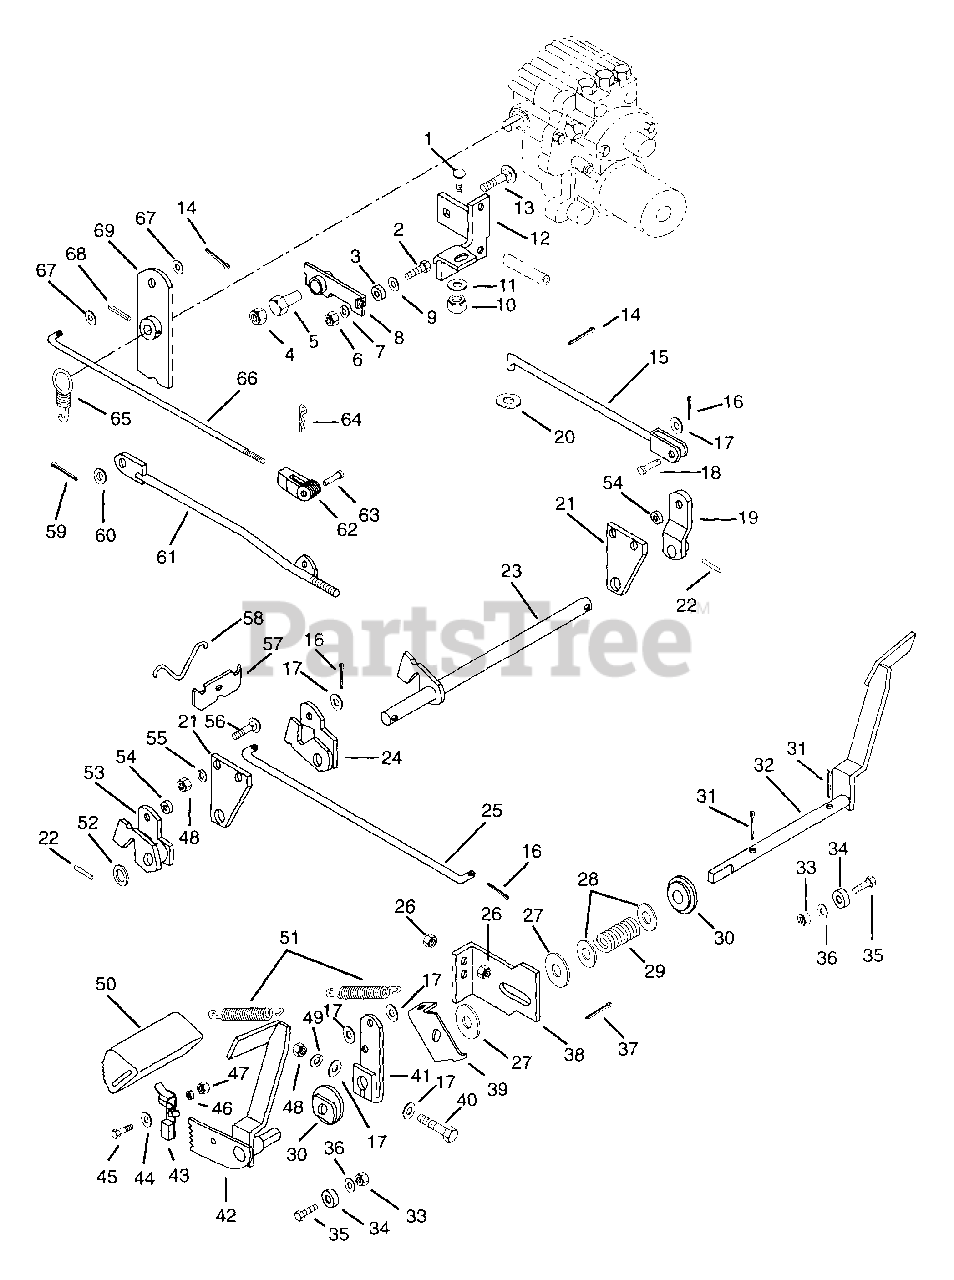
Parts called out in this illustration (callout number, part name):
1	BLT-RDHDSQNK .50-13X1.25GR5PL
2	BLT-HEX .25-20X1.00 GR2
3	BRG BALL DBL .250X.638X.438
4	NUT-LK-NYL.312-18 PL
5	ECCENTRIC
6	NUT-LK-CTR .250-20 PL
7	WSHR-LK .250X.047 LT PL
8	DETENT ARM
9	WSHR-FL-STL .281X1.250X.048PL
10	NUT-LK-CROWN .50-13 GR C PL
11	WSHR-FL-STL .531X1.062X.095 PL
12	MOUNT WELDMENT
13	BLT-RDHDSQNK.31-18X2.25 PL
14	PIN-COTR .09X.75 PL
15	BRAKE ROD
16	PIN-COTR .12X.75 PL
17	WSHR-FL-STL.406X.812X.065PL
18	PIN-CLEV .373X1.12 YWZC
19	BRAKE ARM
20	WSHR-FL-STL .382X.812X.023 PL
22	PIN-GRV .250X1.25 TP A
23	BRAKE SHAFT
25	BRAKE ROD
26	NUT-LK-CTR .50-13
27	WSHR-FL-STL .755X2.000X.125
28	WSHR-FL-STL .755X1.375X.062 PL
29	SG-COMP .148X1.23X2.53 WLD87
30	BSHG-FLG .750X1.750X.875X2.125
31	PIN-COTR .18X1.25 PL
32	L H LEVER
33	NUT-LK .312-18 GR A PL
34	SPACER .344X1.000X.375
35	BLT-HEX .31-18X.88 PL GR2
36	WSHR-FL-STL .38X.875X.083 PL
37	PIN-COTR .09X1.0 PL
38	NEUTRALIZER PLATE
39	NEUTRALIZER ARM
40	BLT-HEX .38-16X2.25 GR2
41	ARM-BRAKE
42	R H LEVER
43	BRAKE LATCH
44	WSHR-FL-STL.281X.62X.065 PL
45	BLT-HEX .25-20X.75 PL GR2
46	SPACER BUSHING .37 X .26 X .14
47	NUT-LK-CTR .250-20 PL
48	NUT-HEX .375-16
49	WSHR-LK .375X.094 MED PL
50	PEDAL COVER
51	SG-TENS .090X.75X3.50 WLD 34
52	WSHR-FL-STL .754X1.125X.062 PL
53	BRAKE ARM
54	GROMMET
55	WSHR-LK .375X.115 HVY PL
56	BLT-RDHDSQSHNK .38-16X1.00 PL
57	BALANCE LINK
59	PIN-COTR .12X1.0 PL
60	WSHR-FL-STL .531X1.062X.095 PL
61	NEUTRALIZER ROD
62	YOKE, .312-24 X 2.25
63	PIN-CLEV .312X.822 HDND PL
64	PIN-HAIR INT .08X.18X1.18
65	SG-TENS .080X.75X2.81 WLD 20
66	SHIFT ROD
67	WSHR-FL-STL .323X.625X.062 PL
68	PIN-ROLL .250X1.38
69	SHIFT ARM
